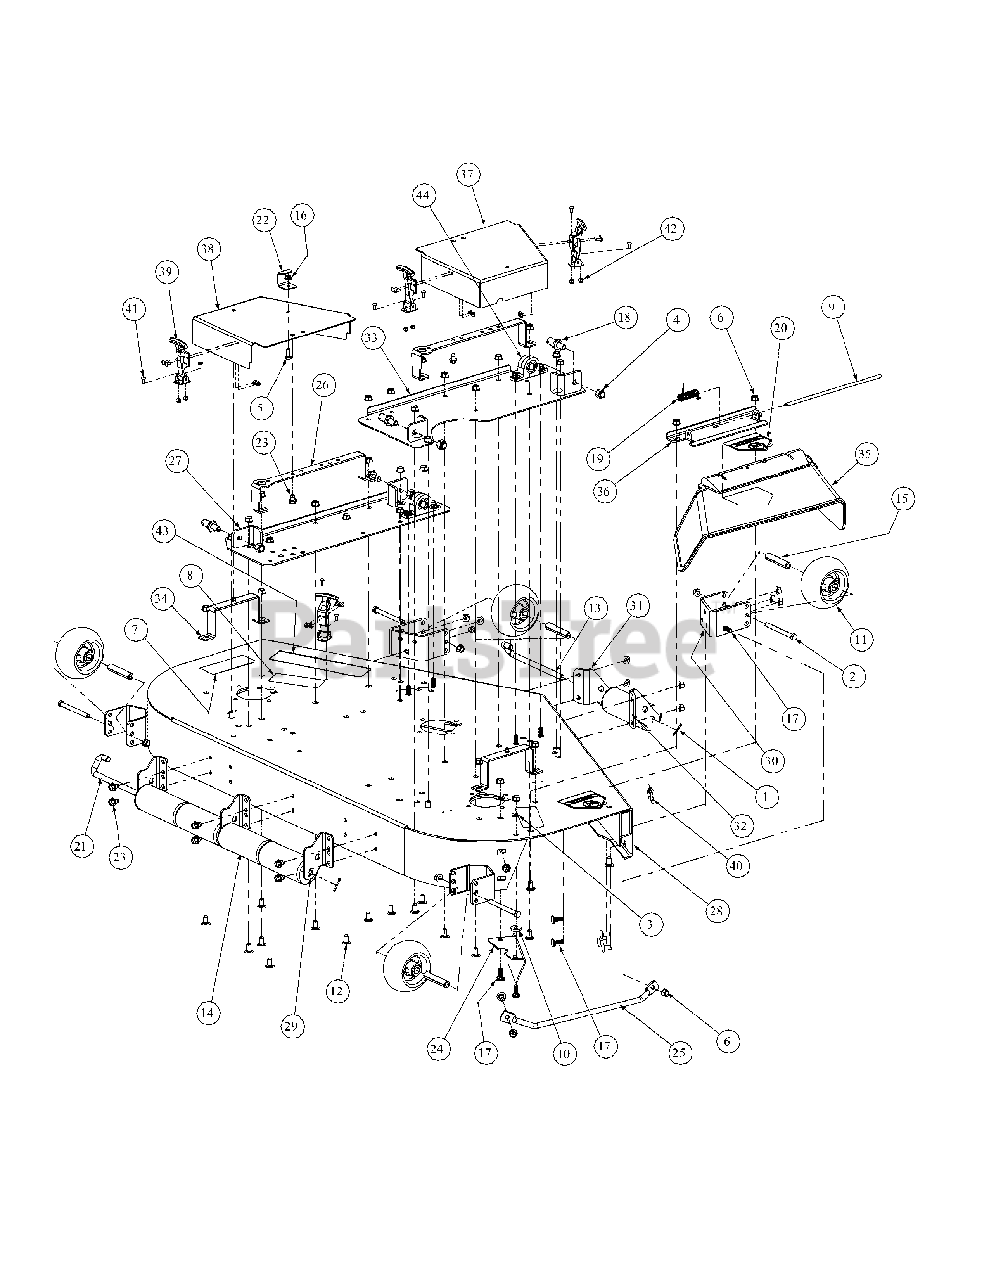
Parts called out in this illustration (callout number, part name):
1	Cotter Pin, .125 Dia x 1.0
2	Hex Cap Screw, 3/8-16, 3.75
3	Flat Washer, 3/8
4	Lock Nut, Nylon Insert, 1/2-13
5	Hex Cap Screw, 5/16-18 x 3/4
6	Hex Nut, 3/8-16 Flange Lock
7	Decal Rotating Blade
8	Decal, Warning Shield Missing
9	Defllector Chute Rod
10	Idler Washer
11	Complete Wheel, 5.00 Dia.
12	Carriage Bolt, 3/8-16 x .75 Lg.
13	Roller Pin. 1/2 Dia. x 7.31 Lg.
14	Front Roller
15	Wheel Spacer
16	Hexflange Lock Nut, 5/16-18
17	Carriage Bolt, 3/8-16 x 1
18	Pin, 5/8 Dia. x 1.2 Lg.
19	Spring Torsion, 0.4 ID x 2.16 LG
20	Decal, Danger Hands and Feet
21	Roller Pin
22	Tension Rod Stop Bracket
23	Hex Index Washer Screw, 3/8-16, .5
24	Chute Bracket
25	Finger Guard
26	Cover Support
27	Left Hand Mount, Deck Bracket Assembly
28	54 Deck Assembly
29	Roller Mount Bracket
30	Anti-Scalp Wheel, Front Mount Bracket
33	Deck Bracket Assembly
34	Outer Belt Cover Support Assembly
35	Deflector Chute
36	Deflector Chute Bracket
37	Right Hand Belt Deck Cover Weldment
38	Left Hand Belt Deck Cover Weldment
39	T-Handle Draw Latch
40	Decal, 54"
41	Phillips Head Screw, 10-32
42	Lock Nut, Nylon Insert, 10-32
43	Mower Deck Label
44	Pillow Block
